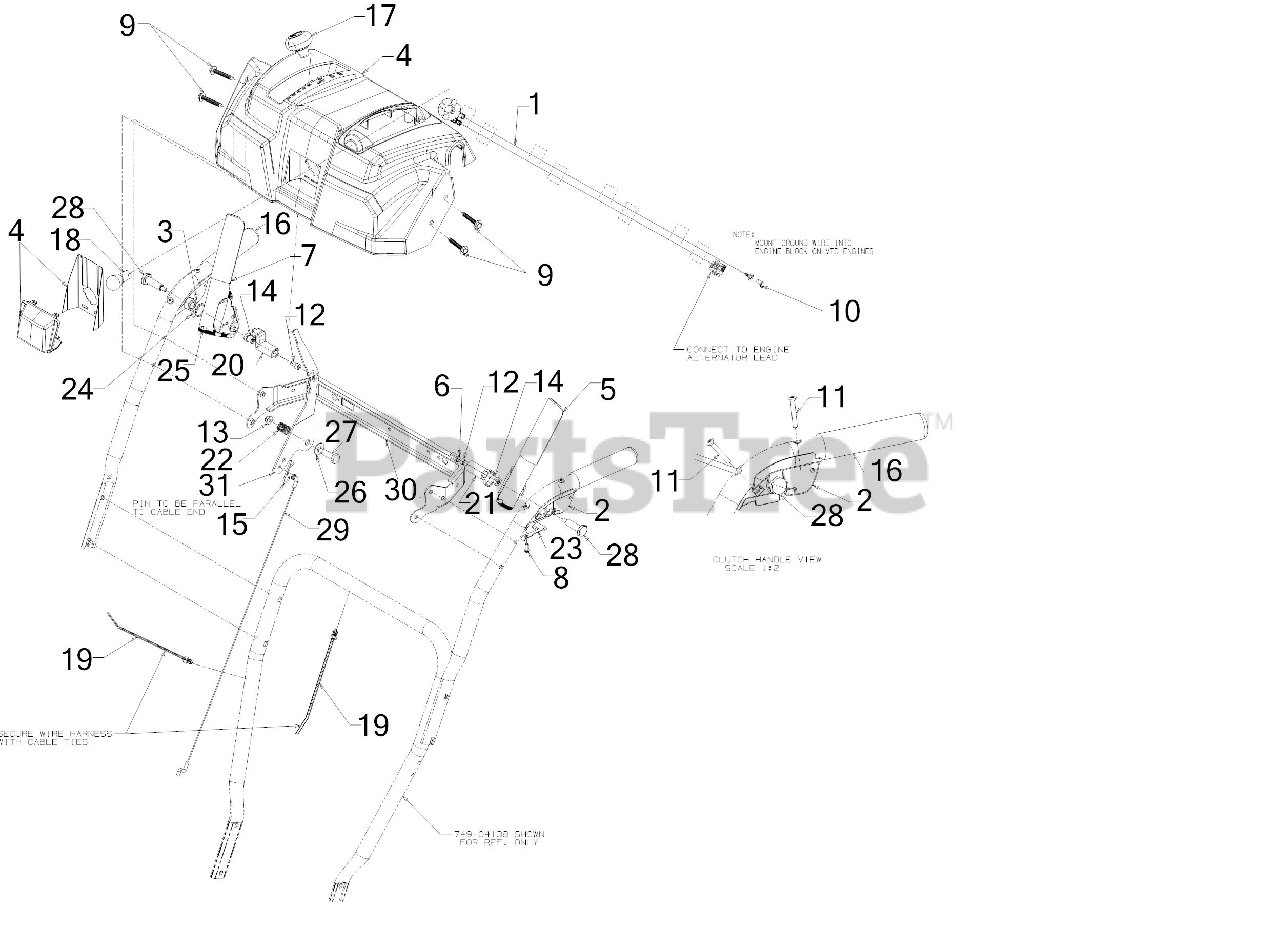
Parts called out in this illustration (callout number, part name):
1	LIGHT HARNESS ASSEMBLY
2	CLUTCH LOCK HANLE ASSEMBLY (LH)
3	CLUTCH LOCK HANLE ASSEMBLY (RH)
4	HANDLE PANEL ASSEMBLY (TROY-BILT)
5	HANDLE ASSEMBLY (LH)
7	ENGAGEMENT HANDLE ASSEMBLY (RH) (BLACK)
8	SCREW #8-16 x .50
9	SCREW 1/4-20 x 1.625
10	SCREW 1/4-20 X.500
11	SCREW #10-24 x 1.375
12	SCREW 1/4-20 x .50
13	FLANGE LOCK NUT
14	HEX NUT W/PATCH
15	INTERNAL COTTER PIN
17	SHIFT KNOB
19	PUSH MOUNT TIE
21	CLUTCH LOCK CAM
22	COMPRESSION SPRING
23	CLUTCH SPRING
24	TORSION SPRING
25	RUBBER BUMPER
26	FLAT WASHER
27	SHOULDER SCREW
28	SHOULDER SCREW .437 x 1.345 1/4-20
29	SPEED SELECTOR CABLE (PLASTIC)
